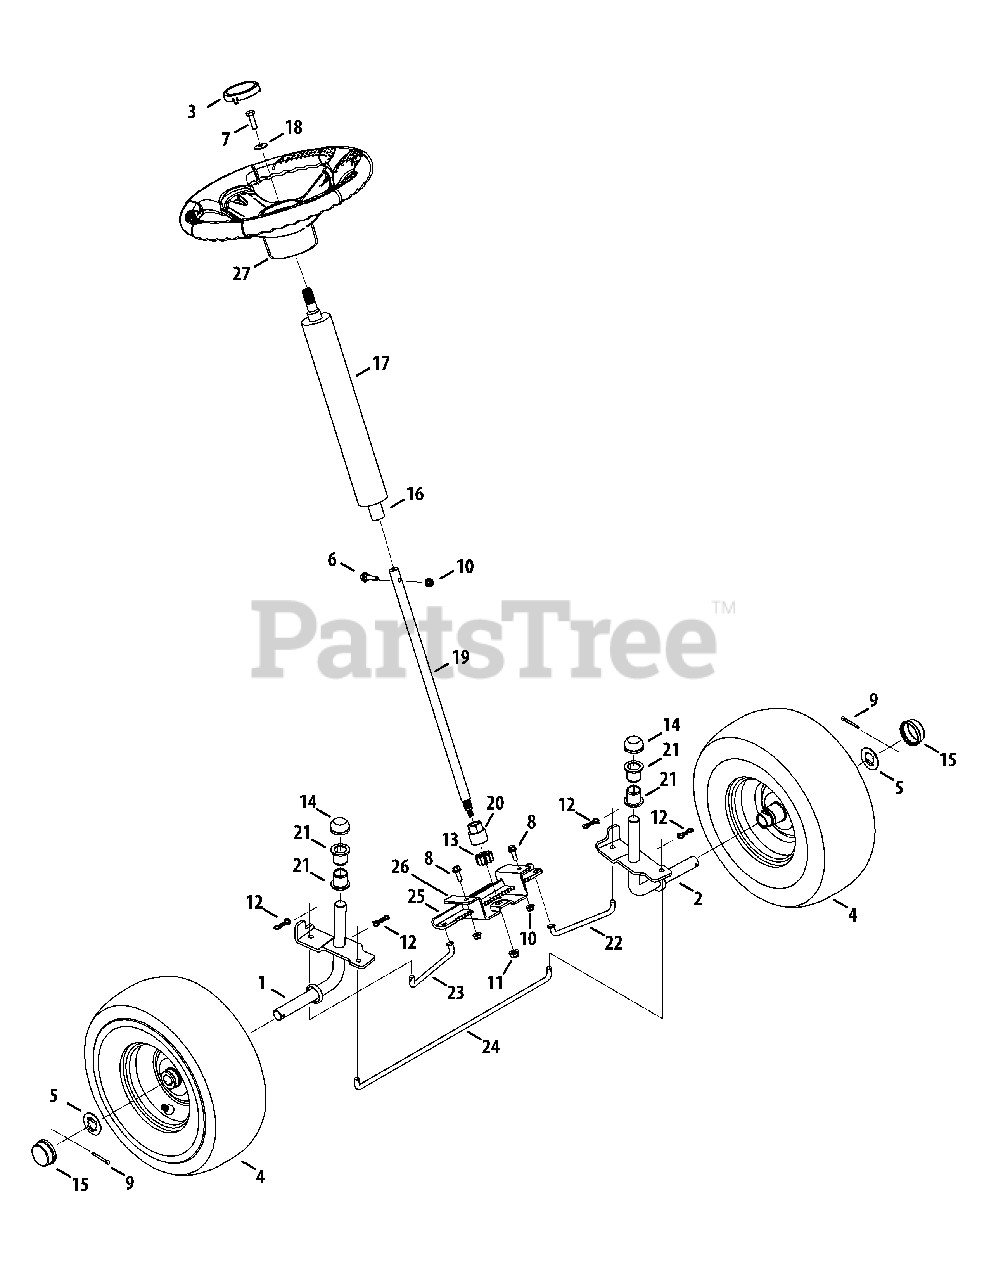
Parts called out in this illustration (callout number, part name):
1	Front Axle Assembly, RH
2	Front Axle Assembly, LH
3	Cap, Troy-Bilt
4	Complete Wheel Assembly
5	Washer, .781 x 1.59
6	Shoulder Screw, .375 x .148 x 1/4-20
7	Hex Head Screw, 5/16-18:1.00
8	Carriage Screw, 1/4-20, .75
9	Cotter Pin, 5/32 x 1.25
10	Flange Lock Nut, 1/4-20
11	Flange Lock Nut, 3/8-16
12	Bow-Tie Cotter Pin, 72
13	Steering Pinion Gear
14	Push Cap, 3/4
16	Tube Assembly, Non-Telescoping
17	Steering Sleeve
18	Bevel Washer, .340X.872X.060
19	Steering Shaft, .625 OD X 18.03
20	Hex Flange Bearing, 5/8
21	Flange Bearing, .760 X .941 X 1.0
22	Steering Rod, LH
23	Steering Rod, RH
24	Front Tie Rod
25	Steering Rack Plate
26	Lower Steering Bearing
27	Steering Wheel, Soft Grip
